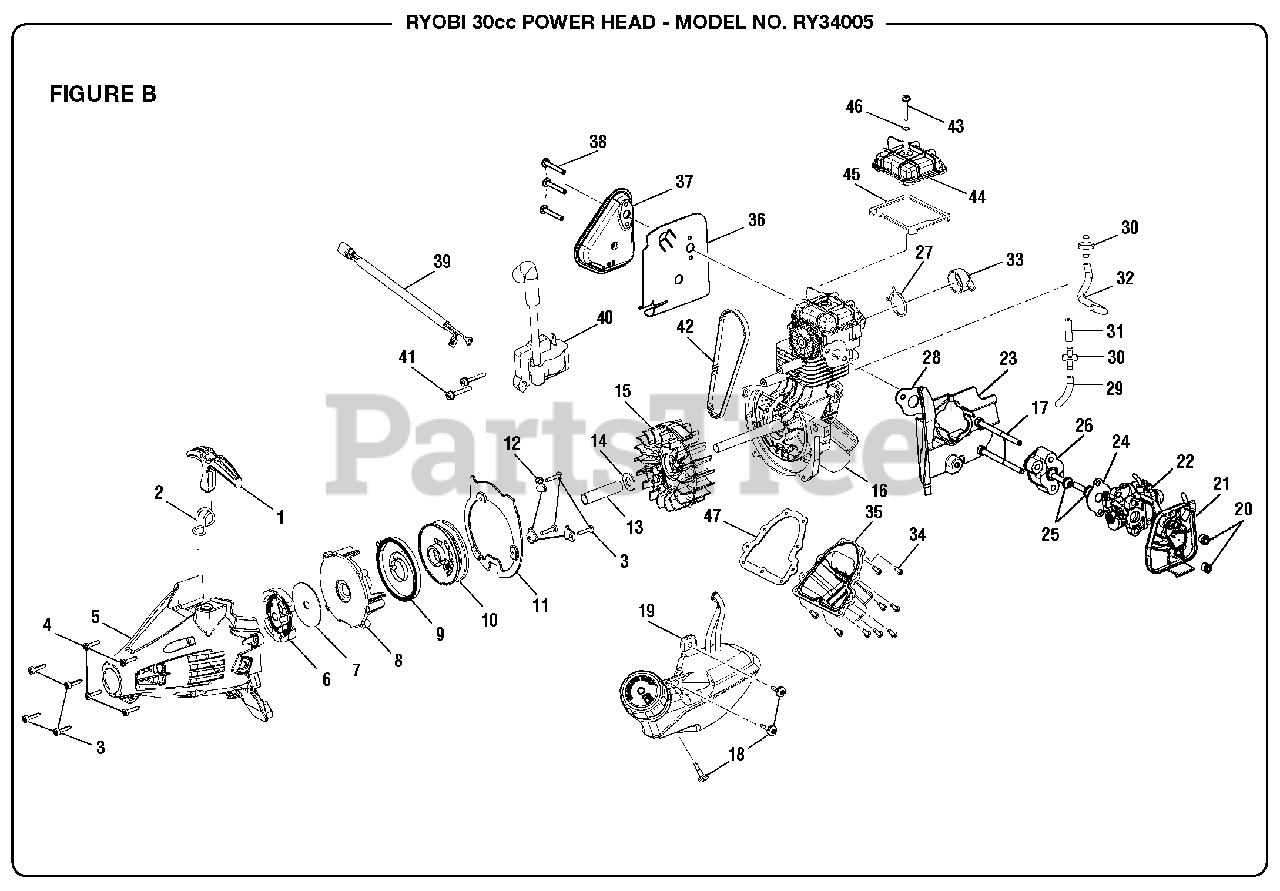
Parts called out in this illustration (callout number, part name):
1	Starter Grip
2	Starter Rope (42 in)
3	Screw (M4 x 18 mm)
4	Screw (M4 x 16 mm)
5	Starter Housing Assembly
6	Clutch Assembly
8	Starter Baffle
9	Spring & Container
10	Starter Pulley
12	Pulley Retainer
13	Spacer Tube
14	Washer
15	Flywheel Assembly
16	Short Block Assembly
17	Bolt (M5 x 63 mm)
18	Screw (M4)
19	Fuel Tank & Cap Assembly
20	Hex Nut (M5 x 0.8)
21	Air Filter Base
22	Carburetor Assembly
23	Air Baffle
24	Carburetor Gasket
25	Screw (M5 x 23 mm)
28	Heat Dam Gasket
29	Breather Hose
30	Check Valve
31	Breather Hose
32	Breather Hose
33	Breather Fitting
34	Screw (M4 x 12 mm)
36	Muffler Gasket
37	Muffler Assembly
38	Muffler Bolt (M5 x 42 mm)
39	Electrical Lead Wire Assembly
40	Ignition Module
41	Screw (M4 x 19 mm)
42	Timing Belt
43	Screw (M4 x 27 mm Total, w/14 mm Threaded)
44	Cam Cover
